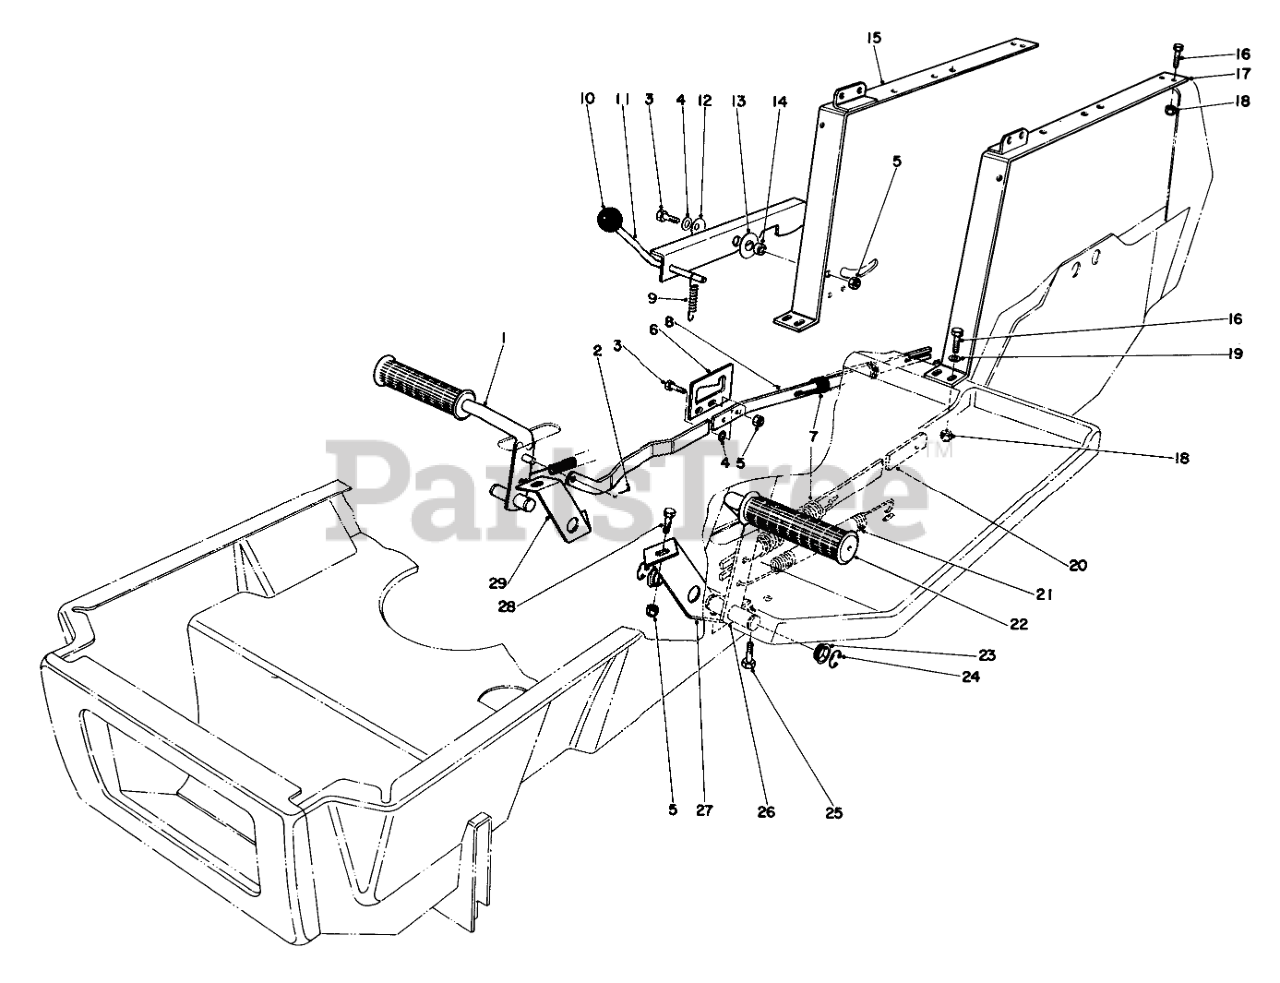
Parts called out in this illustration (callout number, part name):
1	BRAKE PEDAL WA BO
2	PIN-COTTER
3	SCREW-HH
4	WASHER-PLAIN
5	NUT-LOCK, CONE
6	LATCH PLT-BRAKE ROD
7	EXT SPRING O
8	LINK BRAKE ROD WAB
9	CONT ROD SPRING 0
10	Knob
11	PARKING BRAKE WA B
12	WASHER-BELLEVILLE
13	WASHER-PLASTIC
14	SPACER
15	Strap-Rear Body R.H.
16	SCREW-HH
17	Sheave
19	WASHER-FLAT
20	CLUTCH ROD LINK B
21	SPRING-EXTENSION
22	FOOT PAD
23	Nyliner
24	E-RING
25	SCREW-HWHTF
26	CLUTCH PEDAL WA BO
27	LH PEDAL SUPT B
28	SCREW-HH
29	RH PEDAL SUPT B
